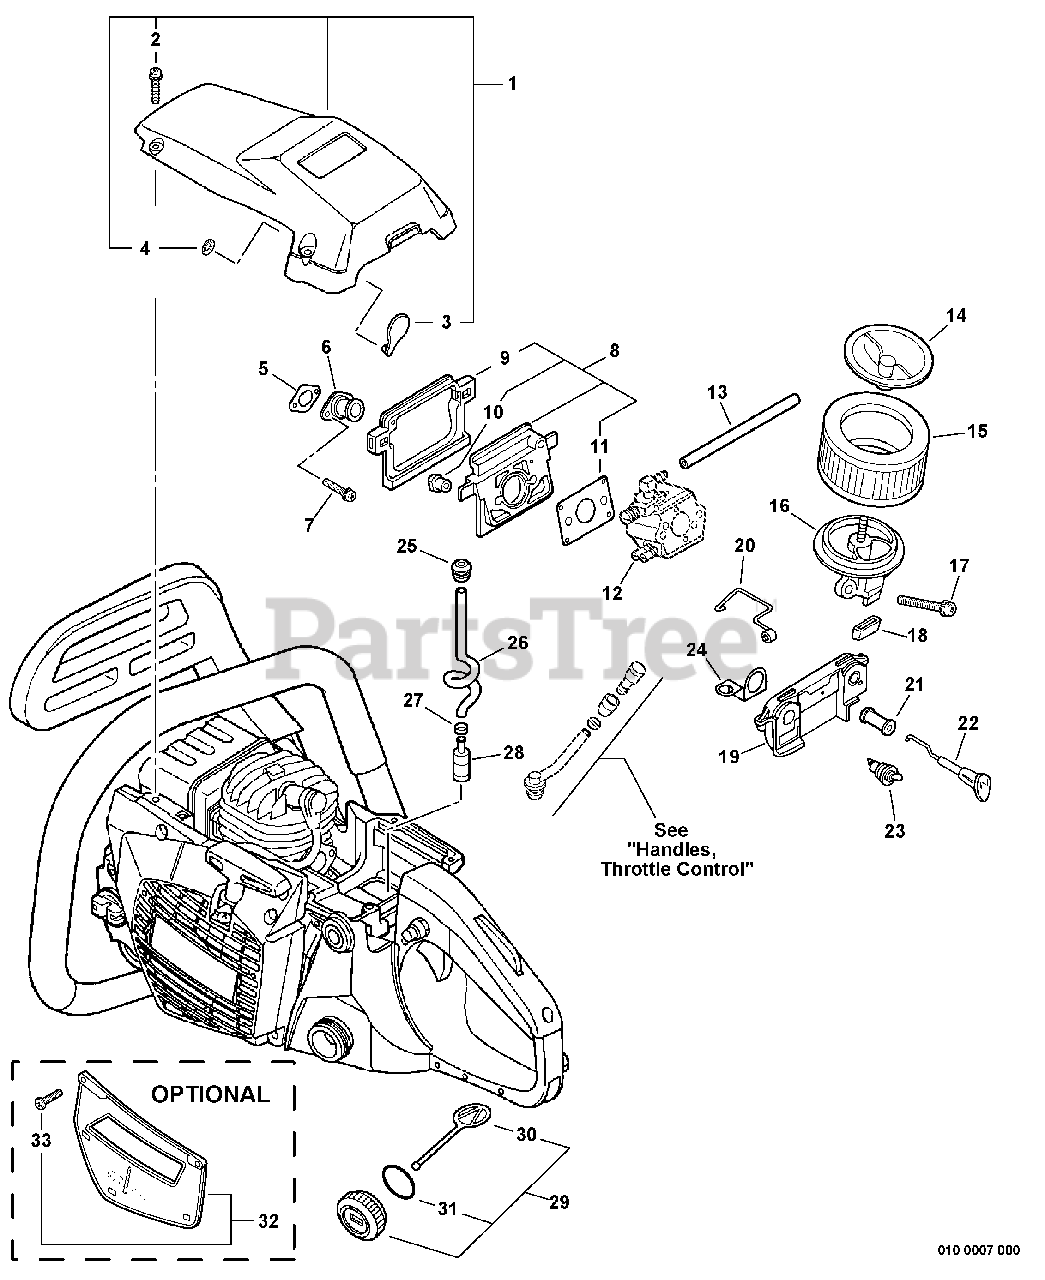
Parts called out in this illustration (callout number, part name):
1	COVER ASSY, CYLINDER
3	PLATE, WIND PROOF
4	PUSHNUT - 4
5	GASKET, INTAKE
6	ADAPTOR, INTAKE
7	SCREW 5×12
8	INSULATOR KIT
9	CUSHION
11	GASKET, INTAKE
12	CARBURETOR
13	PIPE, IMPULSE 3×5×110
14	COVER, AIR FILTER
15	FILTER, AIR
16	ADAPTOR, INTAKE
17	BOLT 5×50
19	BRACKET, SWITCH
20	ROD, THROTTLE
21	GROMMET
22	ROD, CHOKE
23	SWITCH, ON-OFF
24	TERMINAL, SWITCH
26	PIPE, FUEL 3×6×165
27	CLIP Ø6.5 MM
28	FILTER, FUEL
29	CAP ASSY, FUEL
30	CONNECTOR, CAP L= 60 MM
31	O-RING 22
32	SNOW SHIELD KIT
33	SCREW - 4×14
